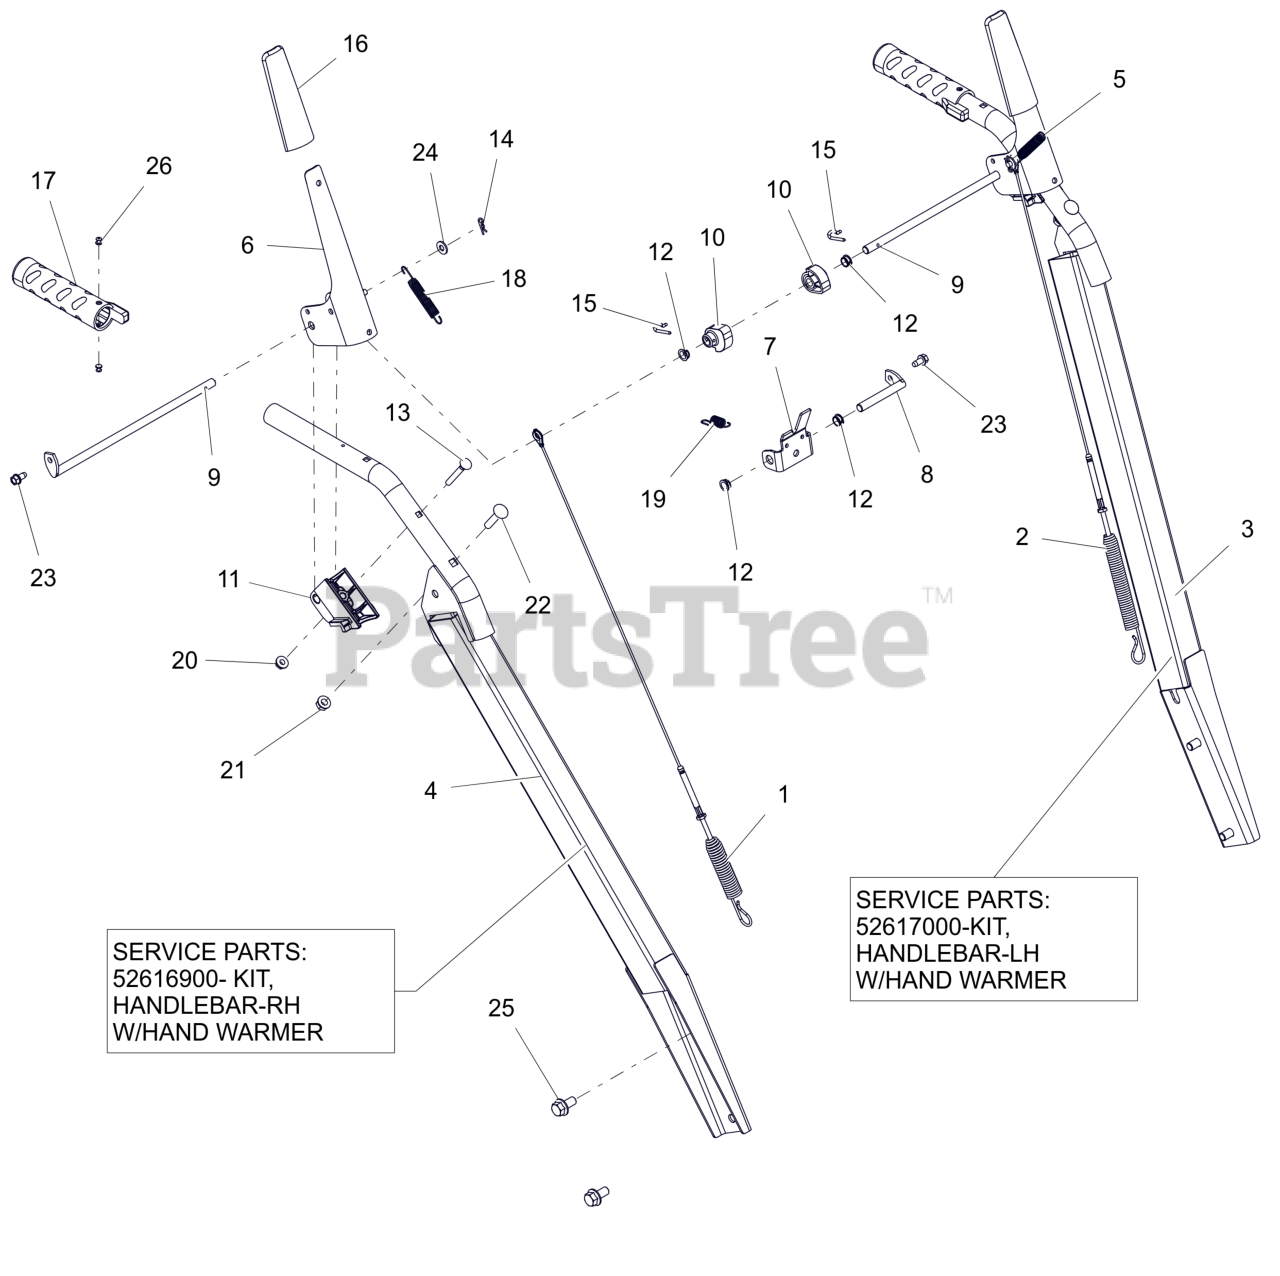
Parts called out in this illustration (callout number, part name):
1	CABLE, AUGER (DELUXE & PRO)
2	CABLE, UPPER TRACTION
3	HANDLEBAR, HEAVYDUTY-PRO LH
3	KIT, HANDLEBAR-LH W/WARM GRIP
4	HANDLEBAR, HEAVYDUTY-PRO-RH
4	KIT, HANDLEBAR-RH W/WARM GRIP
5	LEVER, CLUTCH-LH
6	LEVER, CLUTCH-RH
7	BRACKET, INTERLOCK ARM
8	ROD, PIVOT - INTERLOCK
9	ROD, PADDLE MOUNT - PRO
10	CAM, INTERLOCK
11	BLOCK, CLUTCH PADDLE
12	BUSHING, POLYLINER-.38 SNAPIN
13	BLT-RDHDXLSQNK .25-20X2.0 G5YZ
14	PIN, HAIR #178 .06X.77 ZCC
15	PIN, SPRING CLIP
16	COVER, PADDLE
17	GRIP, HANDLE - HEATED
18	SPRING, EXTENSION
19	SPRING-EXT .047X.438X1.45
20	NUT-LK-CTR-FLG .25-20 ZC120
21	NUT-LK-TOP-FLG .312-18 GF ZCC
22	BLT,RHSN .31-18X1.50 G5 ZCC
23	SCR-TAP .25-20X.50 HWH ZCC
24	WSHR,FLT .281X.625X.065 ZCC
26	RVT-POP #43 .125X.313 STL ZINC
